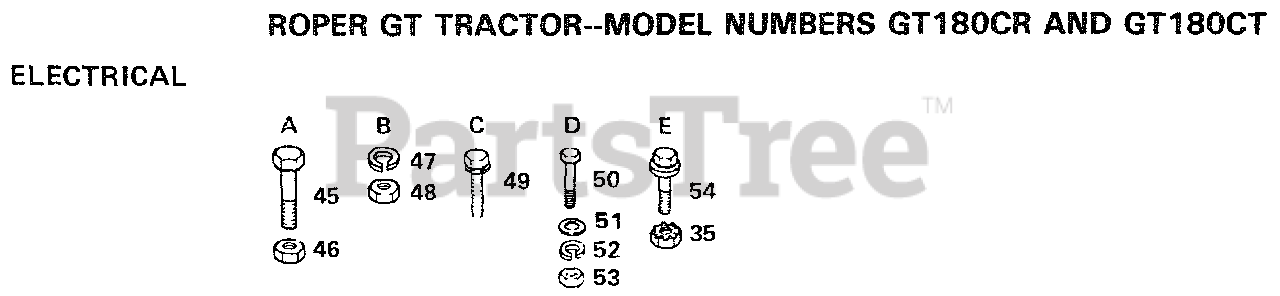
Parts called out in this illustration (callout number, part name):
35	"NUT,KEPS"
45	BOLT
48	NUT
49	SCREW ST
51	WASHER
52	LOCKWASHER
54	SCREW
